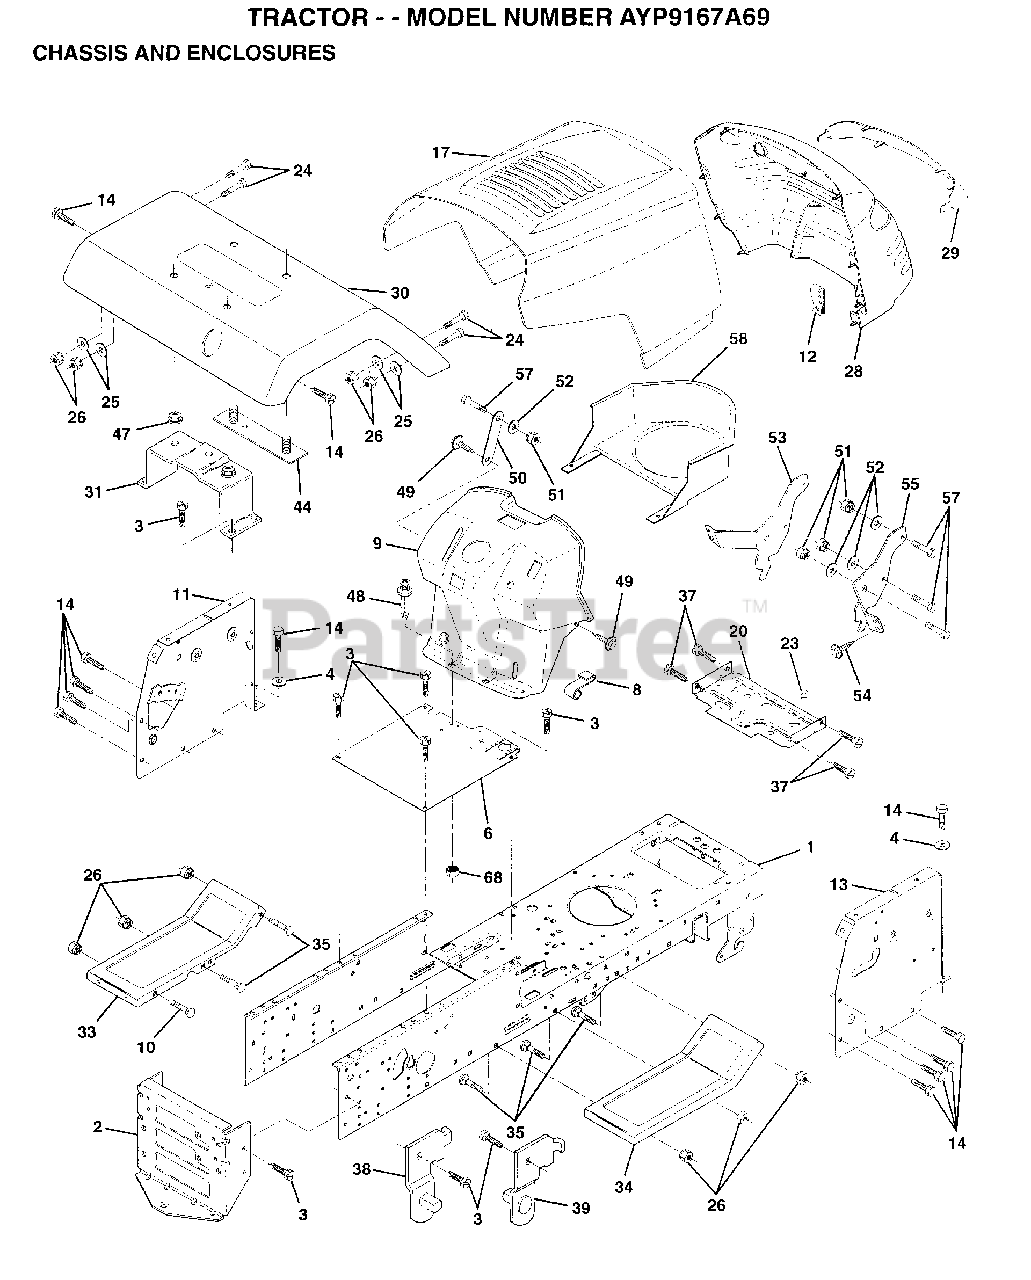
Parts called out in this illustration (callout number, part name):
1	CHASSIS.WLD.11GA
3	SCREW
4	WASHER
8	"CLIP,INSULATOR"
11	PANEL.DASH.LH.A
12	CLIP.TINNERMAN
13	PANEL.DASH.RH.
14	SCREW LT
17	HOOD.STL.PRV.LB
20	PLATE.MTG.BTRY.TK
24	BOLT
25	WASHER
26	NUT
28	GRILL.P/L.EURO.
29	LENS.EURO.W/DECAL
31	BRKT.ASM.FENDER
33	FOOTREST.LT.LT/GT
34	FOOTREST.RH.LT/GT
35	BOLT
37	SCREW LT
38	BRACKET ASM LH
39	BRACKET ASM RH
44	STRAP ASM FENDER
47	NUT-PUSH YT
48	RIVET.PUSH.PLATE
49	SCREW HEX CRT
50	BRACE SUPT DASH
51	NUT
52	WASHER
53	BRACKET.GRILLE.LH
55	BRACKET.GRILLE.RH
58	AIR DUCT
68	NUT
